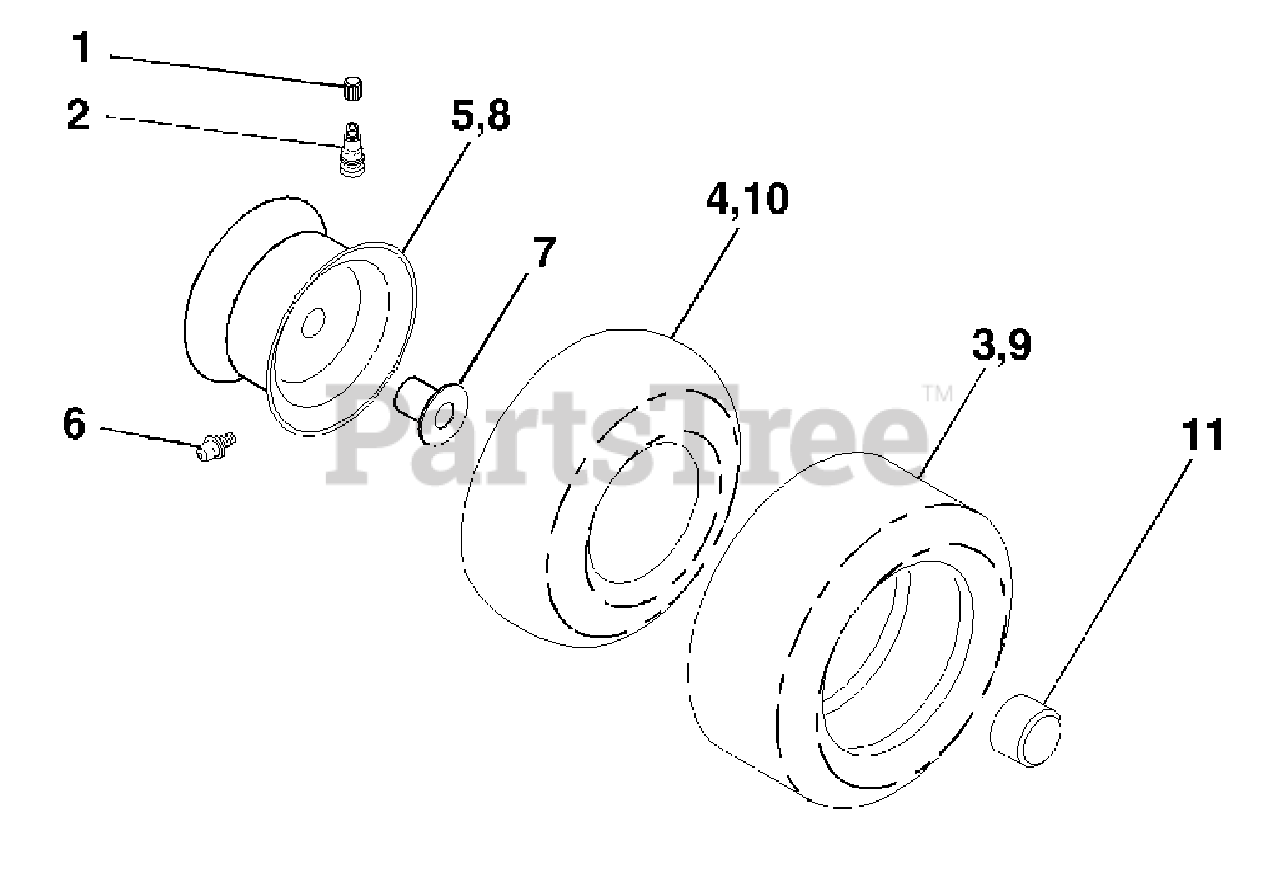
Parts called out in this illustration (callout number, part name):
1	Cap, Tire valve
2	Stem, Valve
3	Tire, Front
4	Tube, Front
5	Rim assembly, 6" front
6	Fitting, Grease
7	Bearing, Flange
8	Rim assembly, 8" rear
10	Tube, Rear
11	Cap, Hub Axle
